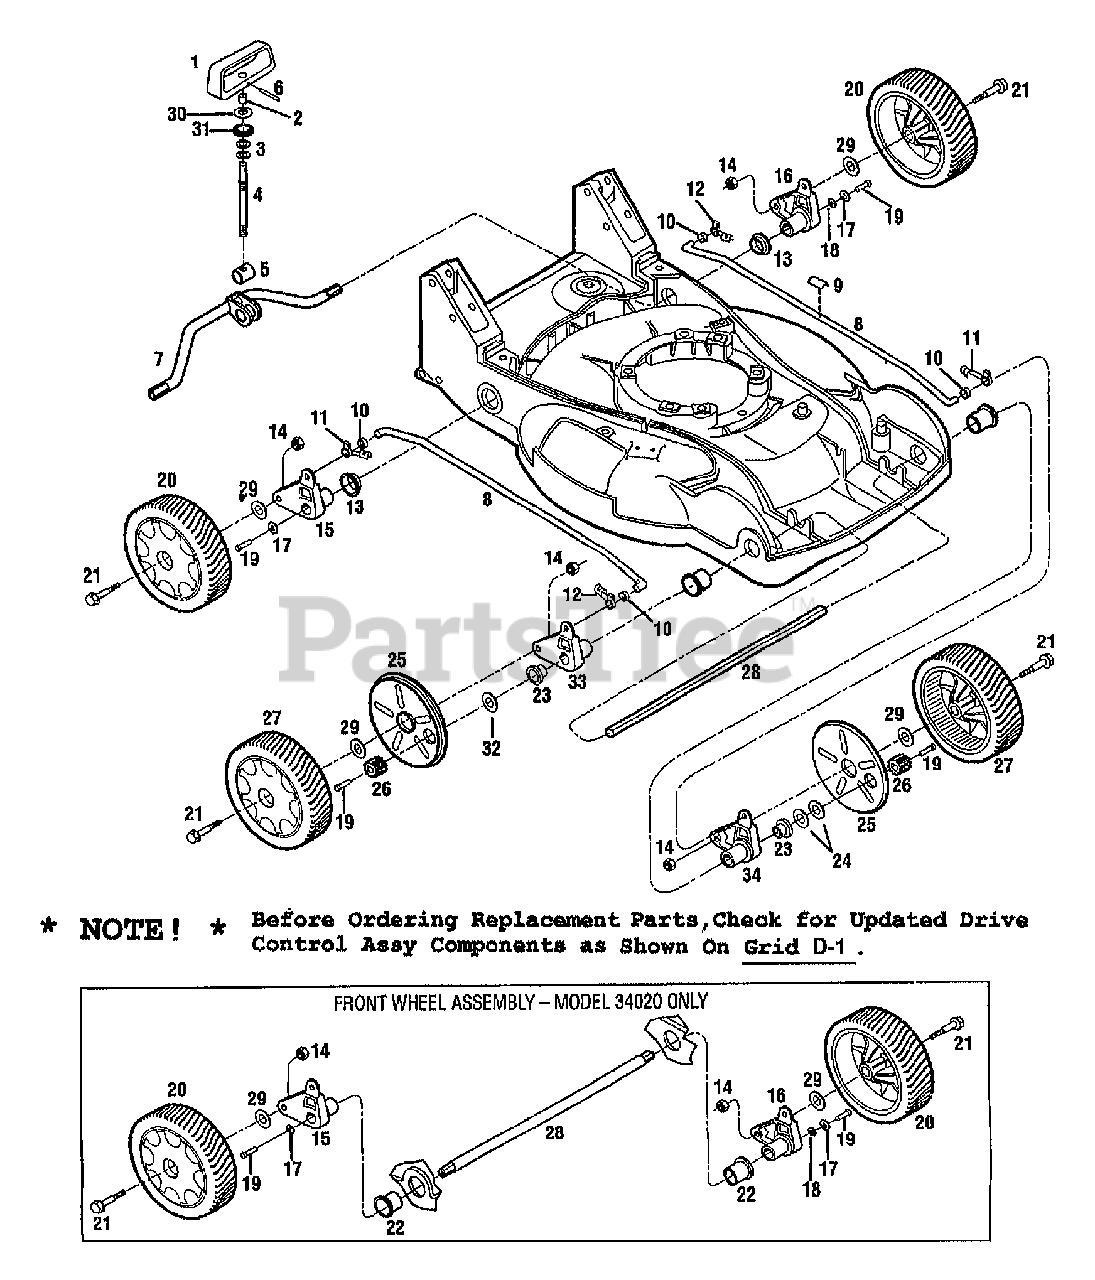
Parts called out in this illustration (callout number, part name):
1	HANDLE-HEIGHT ADJ
2	SPACER-HANDLE
3	WASHER-#.88X.51X.063 ZP
4	SCR-HANDLE ADJUST
5	PIVOT-SCR ADJUST
6	PIN-ROLL .188X1.0
7	AXLE-REAR E-COATED
8	LINK-HEIGHT ADJ PNT
9	DECAL-INDICATOR
10	BEARING-NYLINER
11	CLIP-ROD (RIGHT REAR/LEFT FRONT)
12	CLIP-ROD (LEFT REAR/RIGHT FRONT)
13	BEARING-AXLE ARM REAR
14	NUT-H/LK 3/8-16
15	ARM-AXLE W/BUSHING RH {34020,34021,34022, 34023,34311}(REAR ARM ONLY)
16	ARM-AXLE W/BUSHING LH {34020,34021,34022, 34023,34311}(REAR ARM ONLY)
17	WASHER-.78X.25X.08 ZP @DEP {34020,34021, 34022,34023,34311}
18	WASHER-.5X.25X.06 ZP @DEPL {34020,34021, 34022,34023,34311}
19	SCR-HXSKT 1/4-20X.75
20	ASSM-TIRE & WHEEL {34020,34021,34022,34023, 34311}
21	SCR-SHLDR MOD. RADIUS
22	BRG-AXLE ARM FRONT {34020}
23	BEARING, AXLE (EXCEPT MODEL 34020) (SEE GRID D-7)
24	WASHER-.92X.5X.03 HT {NOT 34020}
24	WASHER-.92X.5X.016 HT {NOT 34020}
25	SHIELD-WHEEL W/STEP {NOT 34020}
26	PINION-DRIVE {NOT 34020}
27	ASSM-TIRE & WHEEL (DRIVE) {NOT 34020}
28	AXLE-FRONT E-COATED {34020}
28	AXLE-DRIVE ROUND W/KEYWAY SLOT)(SEE GRID D-1)
29	WASHER-.88X.406X.09 ZP
30	WASHER-SPEC
31	WASHER-RUBBER
32	WASHER-THRUST .92X.5X.06 {34021,34022,34023, 34311}
33	ARM, AXLE, RIGHT HAND W/AXLE ARM BEARING
34	ARM, AXLE, LEFT HAND W/AXLE ARM BEARING
